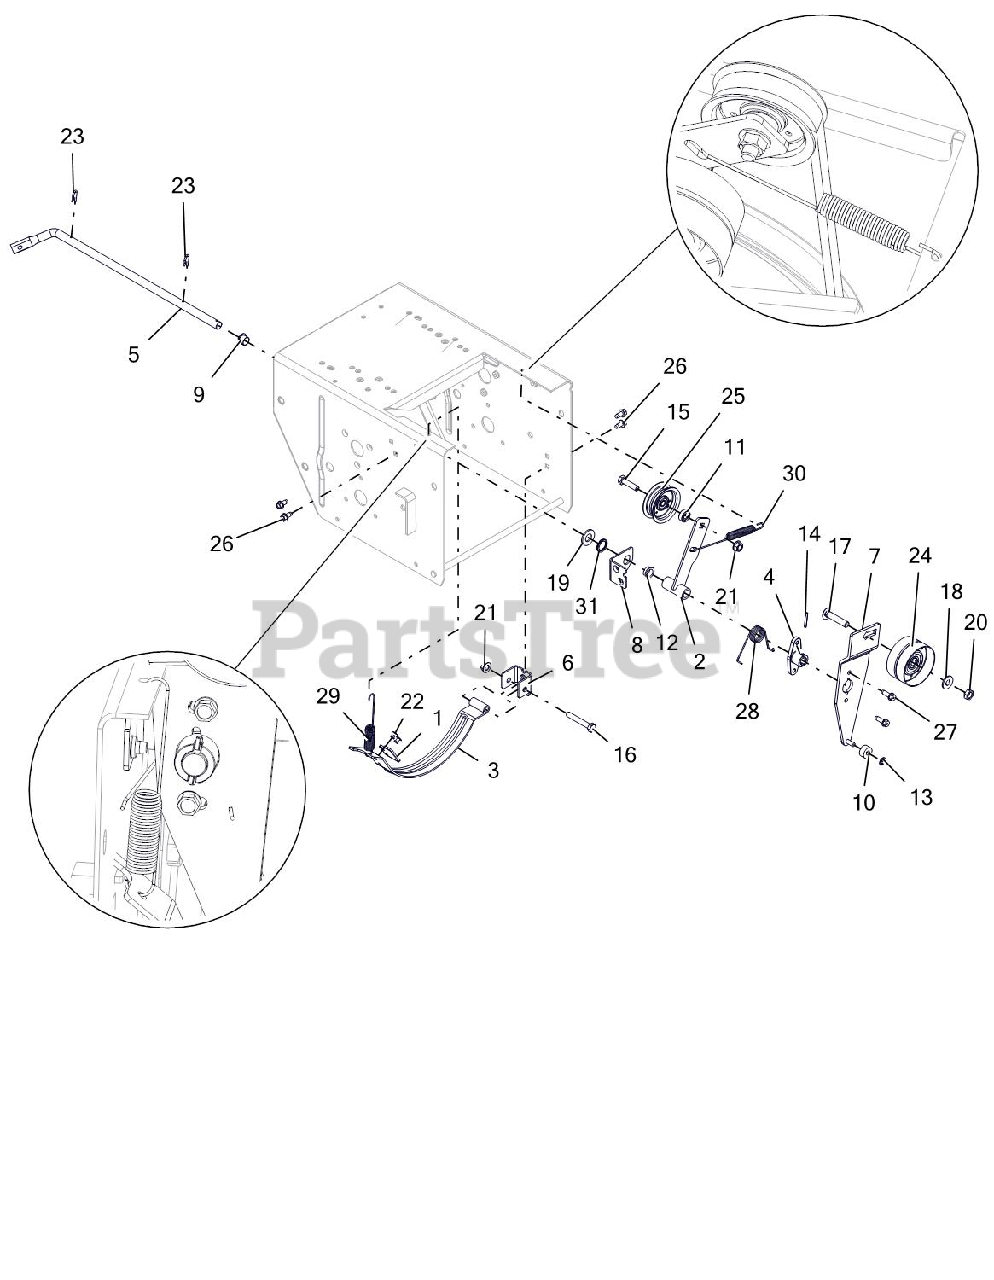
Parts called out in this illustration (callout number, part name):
1	PAD, BRAKE
2	ARM, IDLER-TRACTION
3	ARM, BRAKE-ATTACHMENT
4	HUB, BRAKE ARM
5	ARM, ATTACHMENT
6	PIVOT, BRAKE
7	ARM, IDLER-ATTACHMENT
8	BRACKET, SUPPORT
9	BUSHING, POLYLINER-.50 SPLIT
10	BSHG,SLV .265 X .625 X .375
11	SPCR, BRG .315X.500X.358X.281
12	BSHG,FLANGE .500X.625X.270X.75
13	RG-RTNG-EXT .250X.010
14	PIN-ROLL .125X1.00
15	@BLT-HEX .31-18X1.25 GR5 YWZC
16	@BLT-HEX .31-18X2.00 GR5 YWZC
17	@BLT-RHDSSQNK .38-16X1.75 G5YZ
18	@WSHR-FL-STL.38X.875X.083 YWZC
19	@WSHR-FL-STL.531X1.06X.095YWZC
20	@NUT-LK-CTR-JAM .375-16 YWZC
21	@NUT-LK-TOP-FLG .31-18 YWZC
22	RVT-POP .187 YZ
23	CLIP, SPRING
24	IDLER, FLAT-2.75 OD X .375 ID
25	IDLER, FLAT - 2.00"
26	SCR-TAP .25-20X.50 HWH TR YWZ
27	SCR-TAP-PM .25-20X.75 TR YWZ
28	SG-TORS .067X.88
29	SG-TENS .056X.60X4.40
30	SG-TENS .06X.482X5.35
31	WAVE SPRING .600X.875X.25FH
